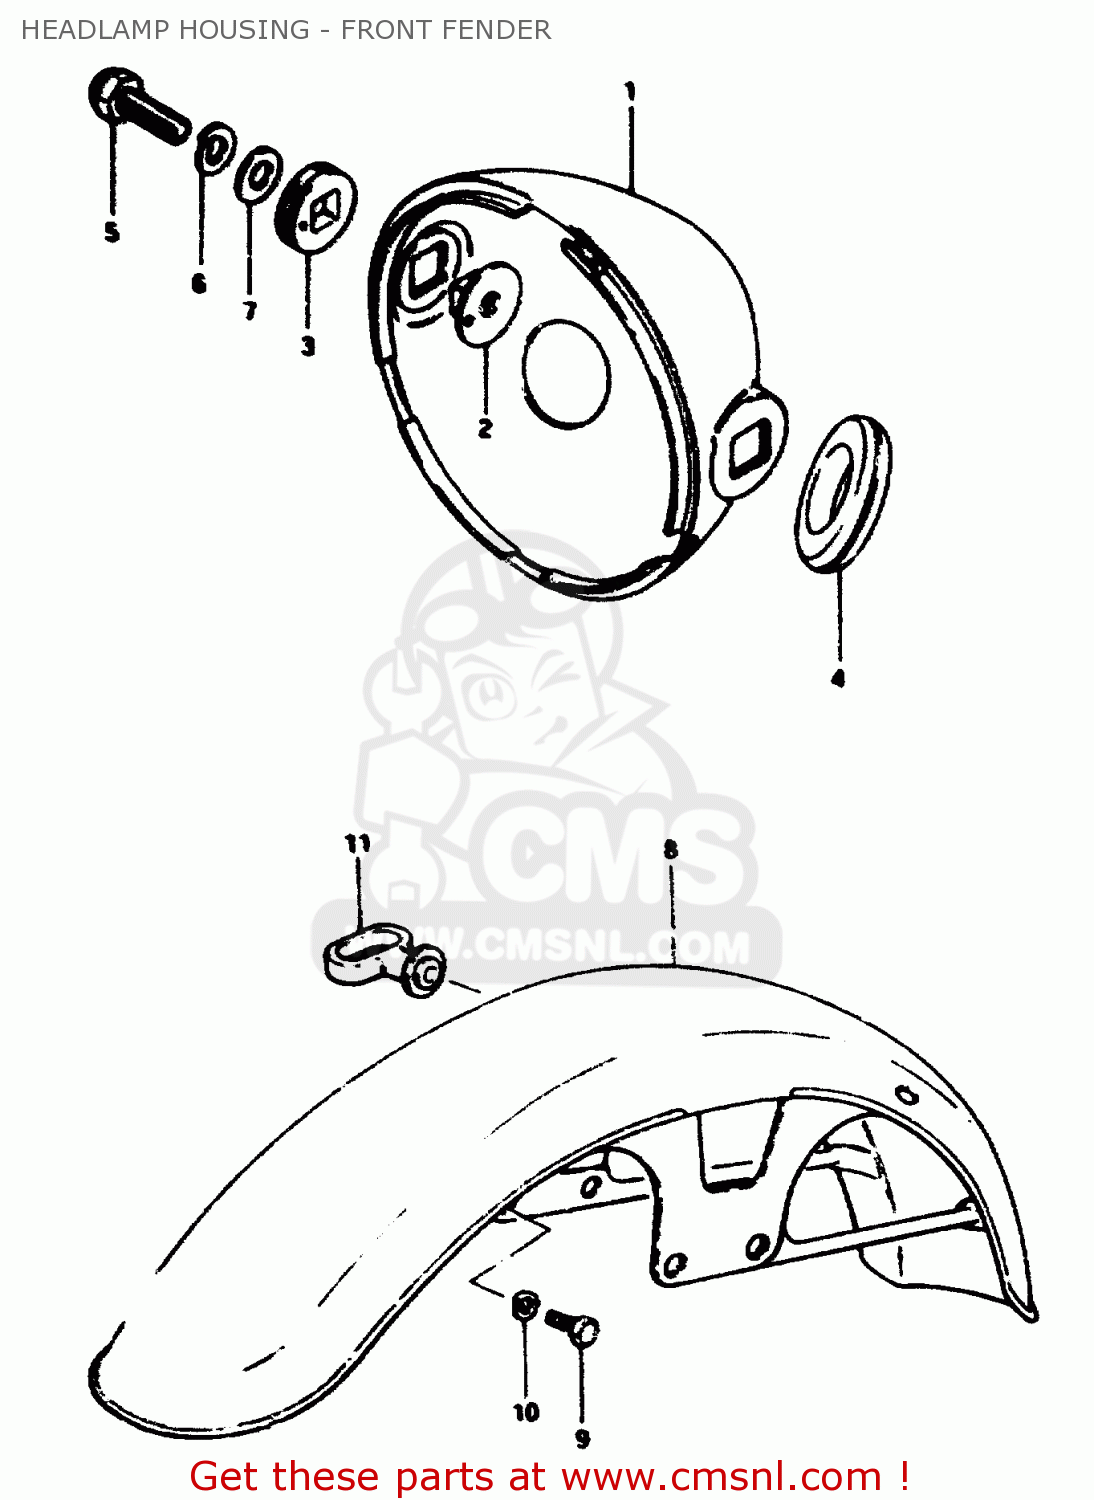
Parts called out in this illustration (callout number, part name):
1	HOUSING, HEADLAMP
2	SPACER,HEADLAMP HOUSING
3	CUSHION,HEADLAMP HOUSING
4	GROMMET,HEADLAMP HOUSING
5	BOLT
6	LOCK WASHER
7	WASHER
8	FENDER, FRONT
9	BOLT
10	LOCK WASHER
11	GUIDE,CABLE
